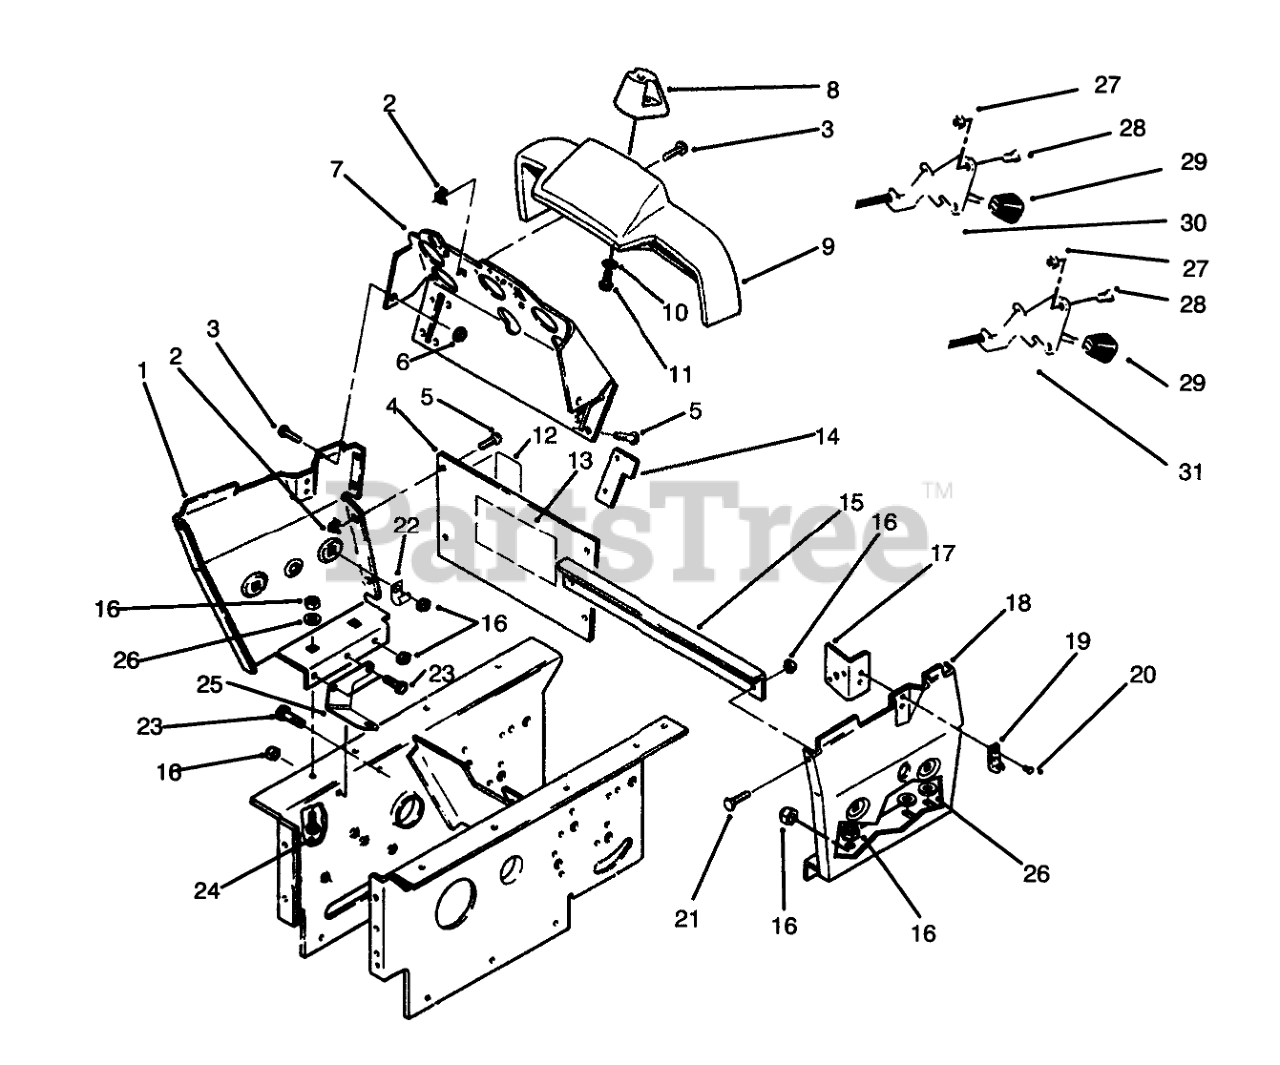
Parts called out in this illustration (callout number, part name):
1	Panel-RH
2	NUT-RETAINED
3	SCREW 1/4-20X.87
4	Plate-Hoodstand, Rear (Incl. Ref. #13)
5	SCREW-PPH
6	NUT-HF
7	ASM-Panel
8	COVER-STEERING SHAFT
9	COVER-CONSOLE 5 GAGE
10	SWIVEL JACK
11	SCREW-#6 PLASTITE
12	DECAL PTO CLUTCH
13	DECAL - DANGER
14	STOP-CHOKE
15	STIFFENER-PANEL B
16	NUT-LOCK, NI
17	BRACKET-SWITCH SU
18	Panel-LH
19	KEEPER-LATCH
20	RIVET-POP
21	SCREW-HH
22	CLIP
23	SCREW-HH
25	Bracket-Control
26	WASHER-PLAIN
27	Nut
28	SCRW-PHC
30	CONTROL-THROTTLE
31	CONTROL-CHOKE
